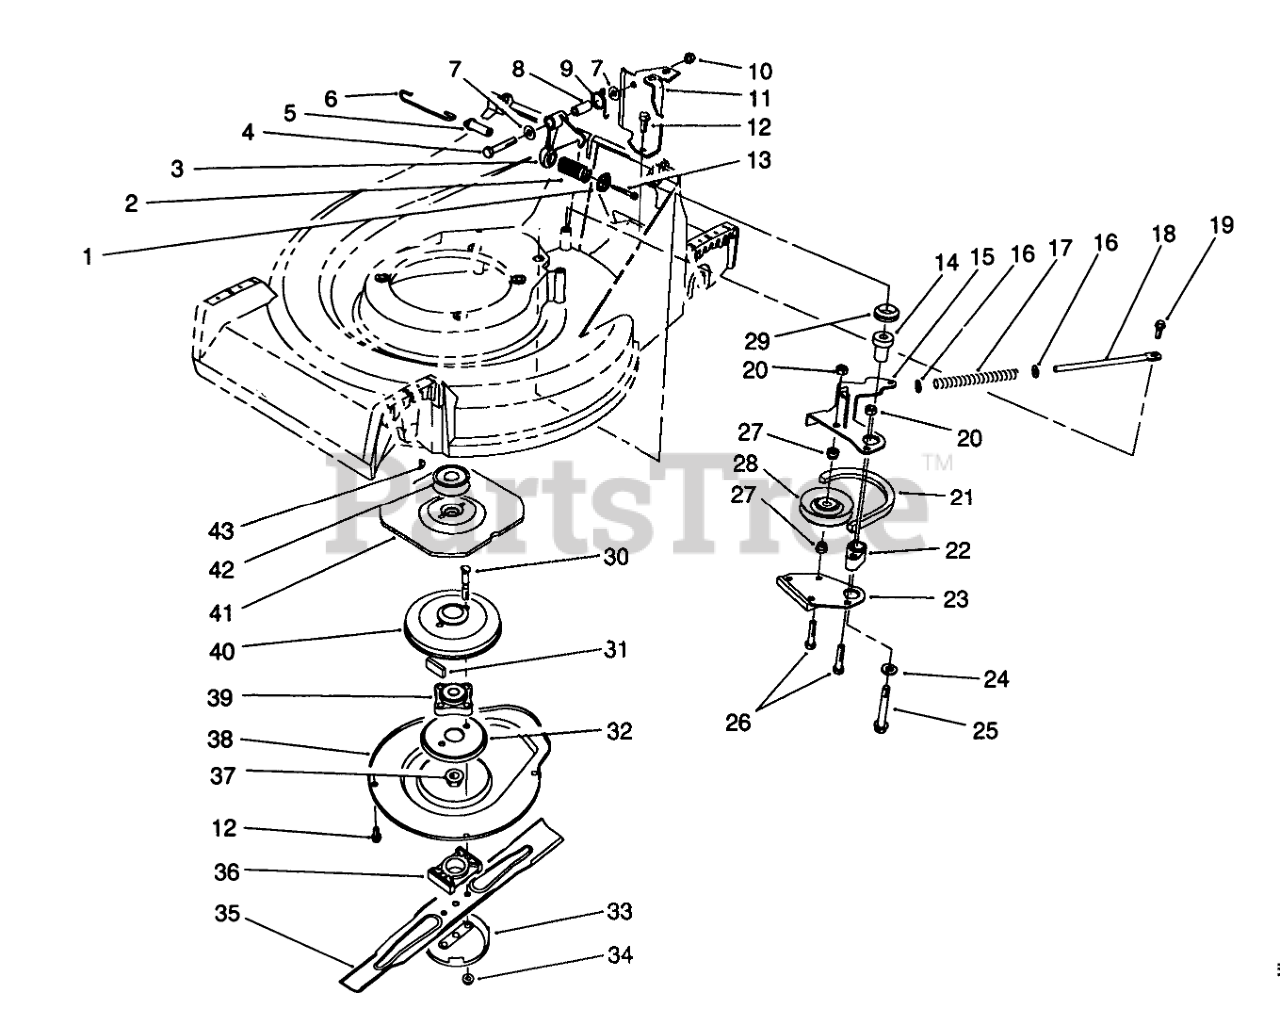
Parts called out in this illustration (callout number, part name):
1	RETAINER-SPRING
2	COMPRESSION SPRING
3	CRANK
4	SCREW-HH
5	SPRING PIN
6	CONTROL LINK
7	WASHER-FLAT
8	STRAIGHT BUSHING
9	TORSION SPRING
11	Bracket-Cable Support
12	SCREW-HWHTF
13	SCREW-HWHTF
14	BBC PM BUSHING
15	Lever
16	PLAIN FLAT WASHER-PLTD
17	COMPRESSION SPRING
18	SPRING ROD
19	SCREW-SHOULDER
20	NUT-LOCK, NI
21	V-BELT
22	BRAKE PLATE HUB
23	BRAKE SHOE
24	WASHER-PLAIN
25	3/8-16 X 2-3/4 CAPSCR
26	SCREW-HH
27	IDLER PULLEY HUB
28	PULLEY-IDLER
29	V-RING SEAL
30	BOLT-BLADE
31	DAMPENER-VIBRATION
32	Screen-BBC
33	Anti Scalp Cup
34	NUT-LOCK
35	Key
36	SPACER-BLADE
37	NUT-LOCK, NI
38	Cover
39	HUB ASM
40	BRAKE DRUM
41	FLYWHEEL - BBC
42	PULLEY
43	KEY-WOODRUFF
